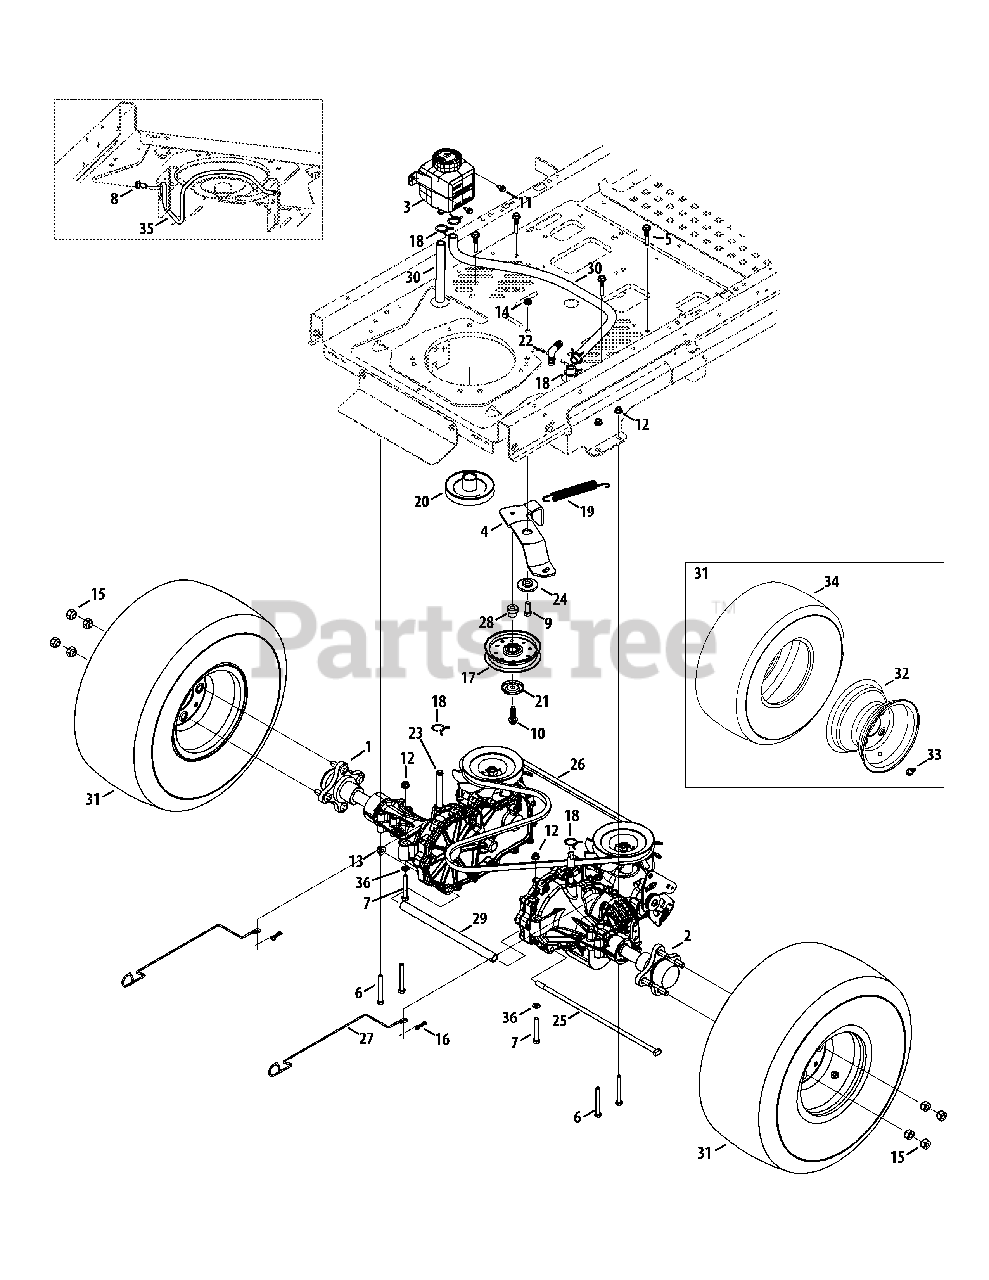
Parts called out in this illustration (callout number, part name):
1	Transmission Assembly, LH
2	Transmission Assembly, RH
3	Expansion Tank Assembly
4	Idler Bracket
5	Keeper Rod, .25 x 1.535
6	Hex Screw, 5/16-18 x 2.75
7	Hex Cap Screw, 5/16-18 x 2.25
8	Hex Washer Screw, 5/16-18 x .750
9	Hex Screw, 3/8-16 x 1.00
10	Hex Washer Screw, 3/8-16 x 1.250
11	Hex Washer Screw, 1/4-20 x .625
12	Flange Lock Nut, 5/16-18
13	Flange Lock Nut, 3/8-16
14	Jam Lock Nut, 3/8-16
15	Lug Nut, 7/16-14
16	Bow-Tie Cotter Pin
17	Idler Pulley, 4.25 Dia.
18	Hose Clamp, .75 Dia. x .312
19	Extension Spring, .75 Dia. x 6.02
20	Engine Pulley
21	Pulley Cap
23	Fitting, 9/16, Barb
24	Shoulder Spacer, .884 x .190
25	Rod, .337 Dia. x 14.75 LG
26	Belt, A-Type x 67.0
27	Bypass Rod
28	Shoulder Spacer
29	Spacer, .75 OD x 11.31 LG
30	Fuel Hose, 1/2 ID
31	Complete Wheel, 22 x 13-6.5
32	Rim Only
33	Valve Tubeless
35	Engine Keeper Rod
36	Flat Washer .330 ID x .630 OD
